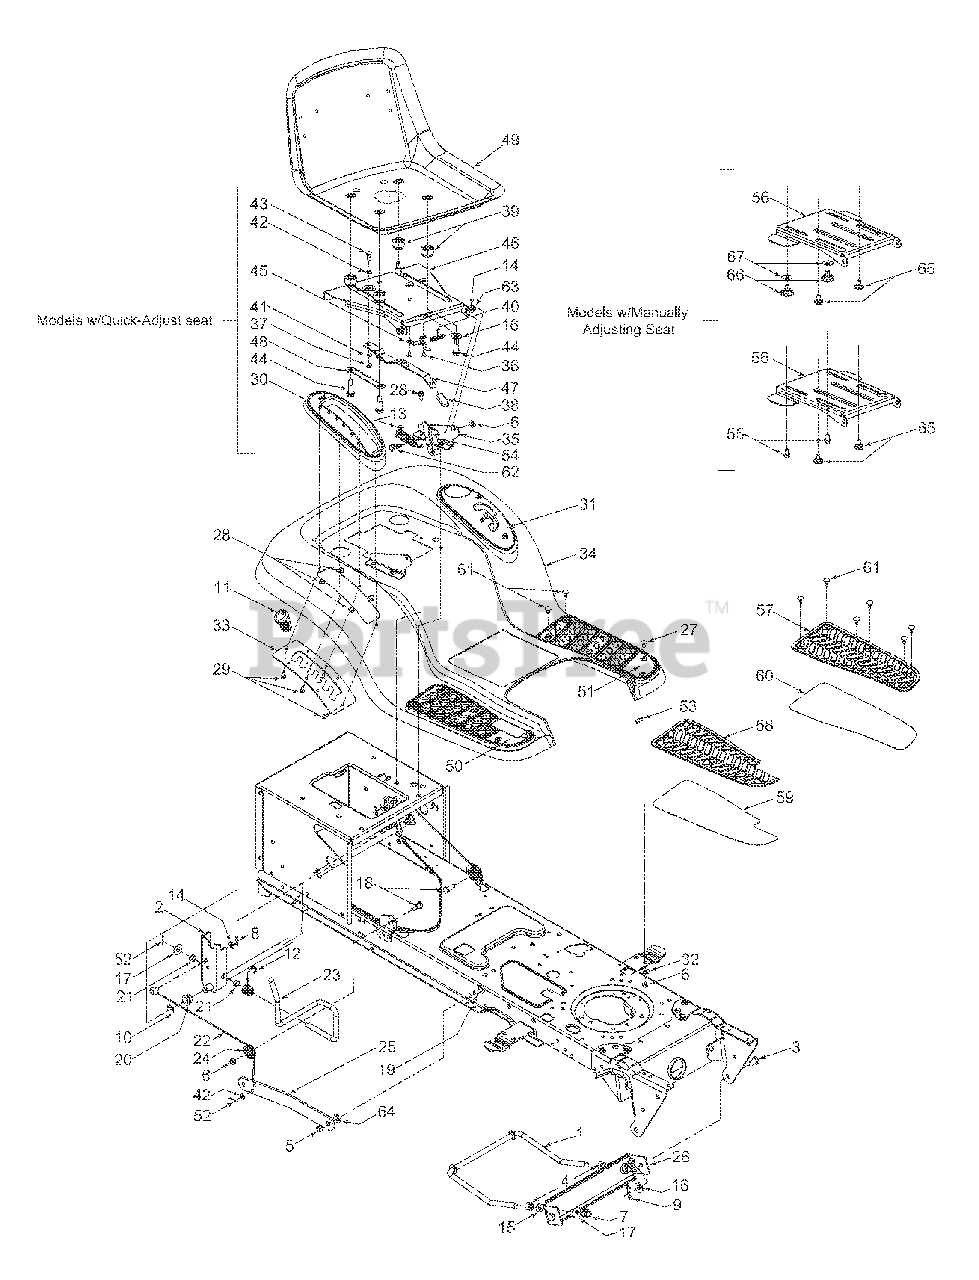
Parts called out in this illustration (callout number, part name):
1	Deck Stabilizer Rod
3	Clevis Pin, .5 x .78
4	Hex Nut, 1/2-13
5	Flange Lock Nut, 3/8-16
6	Flange Lock Nut, 5/16-18
7	Hex Nut, 1/2-13
8	Internal Cotter Pin
9	Internal Cotter Pin
10	E-ring
11	Handle Grip
12	Torsion Spring
13	Extension Spring, .84 x 4.6
14	Flat Washer, 5/16
15	Lock Washer, 1/2
16	Flat Washer, .31 x 1.062 x .134
17	Flat Washer, .51 x 1.12 x .06
18	Hex Cap Screw, 5/16-18 x .62
19	Shoulder Screw, 3/8-16
20	Hex Flange Bearing
21	Snap Flange Bearing
22	Lift Cable, 16.16 (42-inch decks)
23	Lift Handle
24	Roller Pulley
27	Carriage Bolt, 5/16 x .62
28	Self-tapping Screw, 5/16-18 x .75
29	Self-tapping Screw, 1/4-15 x .75
30	Lift Lever Cover
31	Shift Lever Cover w/ Cup Holder
32	Flat Washer, .349 x 1.0 x .063
36	Screw, #10-16 x .375
37	Hex Flange Lock Nut, 1/4-20
38	Seat Adjuster Grip
39	Spacer
40	Compression Spring, .41 x 1.5
41	Spring Washer, .265 x .562 x .025
42	Flat Washer, .344 x .62 x .03
43	Shoulder Screw, .340 x .285,1/4-20
44	Shoulder Screw, .50 x .925, 3/8-16
45	Seat Stop
48	Seat Adjustment Selector
49	High Back Seat, Black
50	RH Foot Pad, Rubber (4-Style Fender)
51	LH Foot Pad, Rubber (4-Style Fender)
52	Cotter Pin
53	Trim Strip
54	Seat Lift Bracket
55	Hex Head Washer Screw, 3/8-16 x .625
57	RH Foot Pad, Rubber (7-Style Fender)
58	LH Foot Pad, Rubber (7-Style Fender)
59	RH Foot Pad, Grit (7-Style Fender)
60	LH Foot Pad, Grit (7-Style Fender)
61	Ratchet Clip
62	Shoulder Screw, .437 x .286
63	Speed Nut, .3125
64	Flat Washer, .531 x .93
65	Shoulder Spacer
66	Knob, 3/8-16
67	Cupped Washer, .39 x 1.12
